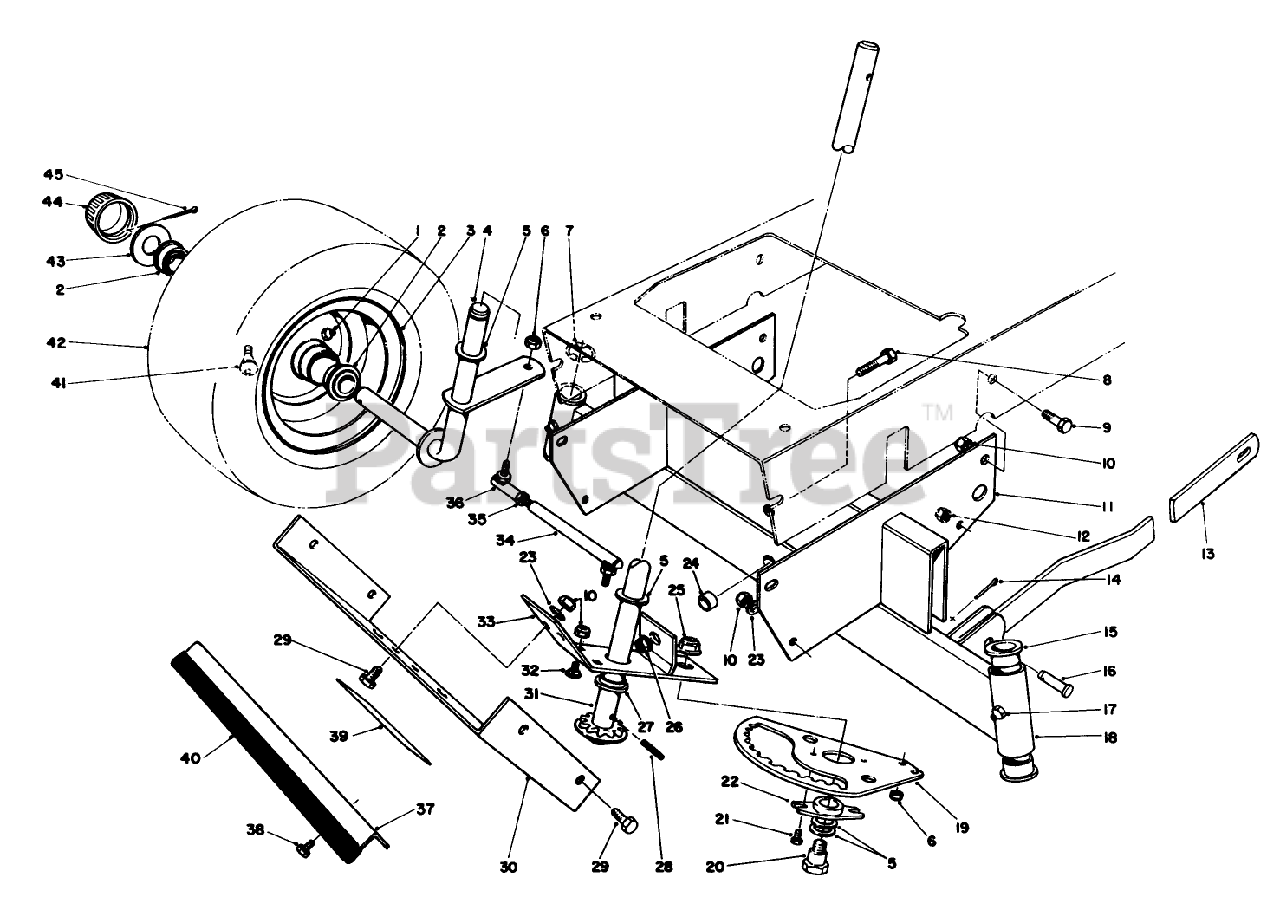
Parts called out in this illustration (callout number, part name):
1	FITTING-GREASE
4	Spindle-R.H.
5	WASHER-THRUST
7	E-Ring
8	SCREW-HH
9	SCREW-HH
10	NUT-LOCK, NI
11	Support-Front Axle
12	NUT-LOCK, CONE
14	PIN-COTTER
15	BEARING-FLANGE
16	PIN-CLEVIS
17	GREASE FITTING
21	SCREW
22	BUSHING-SECTOR
23	WASHER-PLAIN
24	SPACER-AXLE, FRONT
25	NUT-HF
26	NUT-HF
27	BEARING-FLANGE
28	PIN-ROLL, SLOTTED
29	SCREW-HH
31	STRG SHAFT WA
32	SCREW-CARR
33	STRG RACK BRKT WA *B
34	TIE-ROD
35	NUT-JAM
36	JOINT-BALL RH
37	FRONT GUARD *R
38	SCREW-THD ROLL, HWH
40	TRIM-FRONT GUARD
42	TIRE,PNEU.11X4.00X5
43	WASHER-PLAIN
45	PIN-COTTER
